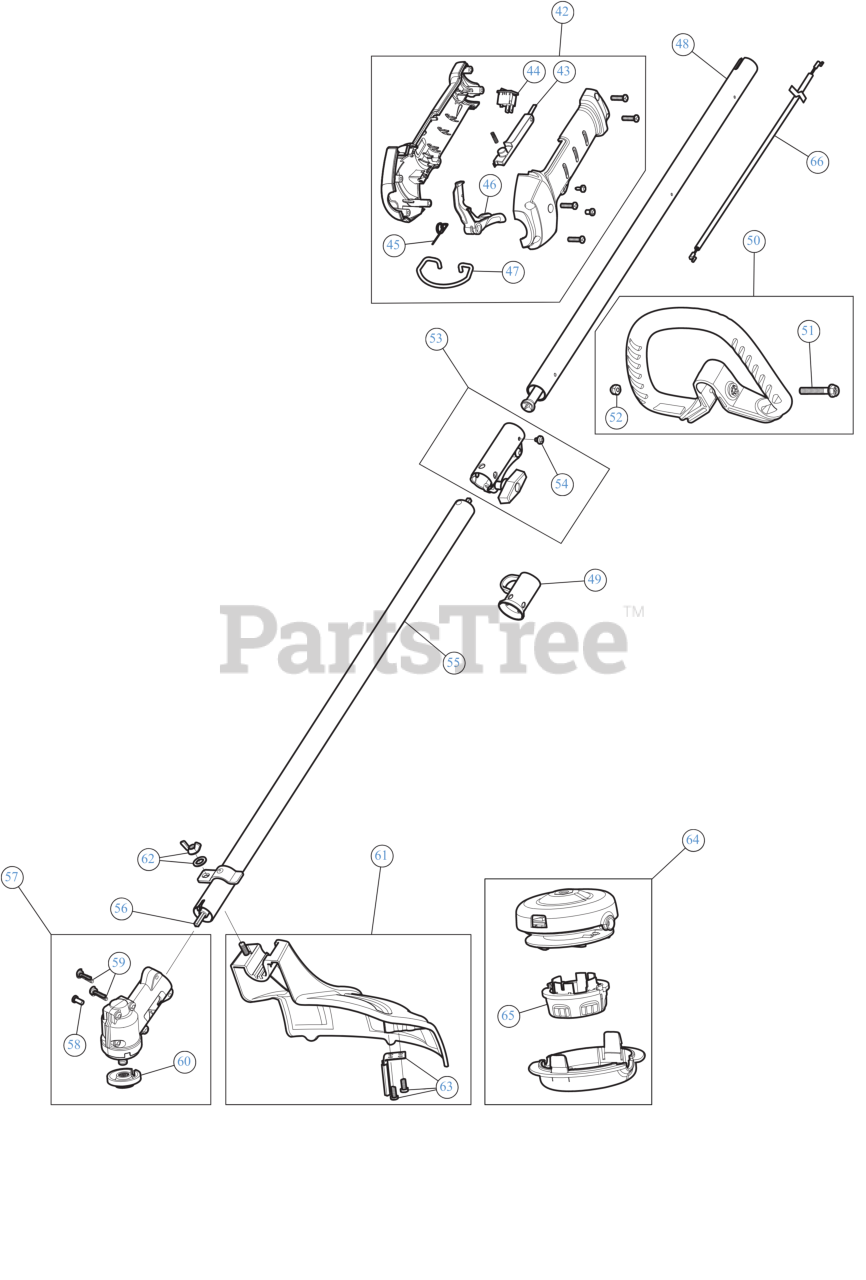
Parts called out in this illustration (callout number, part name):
42	THROTTLE GRIP ASM
43	LEVER LOCK OUT
44	SW, MOMENTARY ON/O
45	SPRING TRIG
46	THROTTLE TRIGGER
47	SHOULDER STRAP CLIP
48	DRIVE SHAFT ASSEMBLY UP
49	HANGER
50	HANDLE ASSEMBLY
51	BOLT 1/4-20X1 1/2
52	NUT 1/4-20 NYLOC
53	COUPLER ASSEMBLY
54	SCREW, 10-32X.250 TA
55	LOWER BOOM ASSEMBLY
56	LOWER DRIVE SHAFT
57	GEARBOX LCBC
58	SCREW, 8-32 x .312 P
59	SCREW #
60	CUTTING HEAD SPACER
61	GUARD/BLADE ASM
62	BLADE GUARD MOUNTING HARDWARE
63	BLADE ASSEMBLY W/HDW
64	CUTTING HEAD
65	BUMP KNOB
66	THROTTLE CABLE
